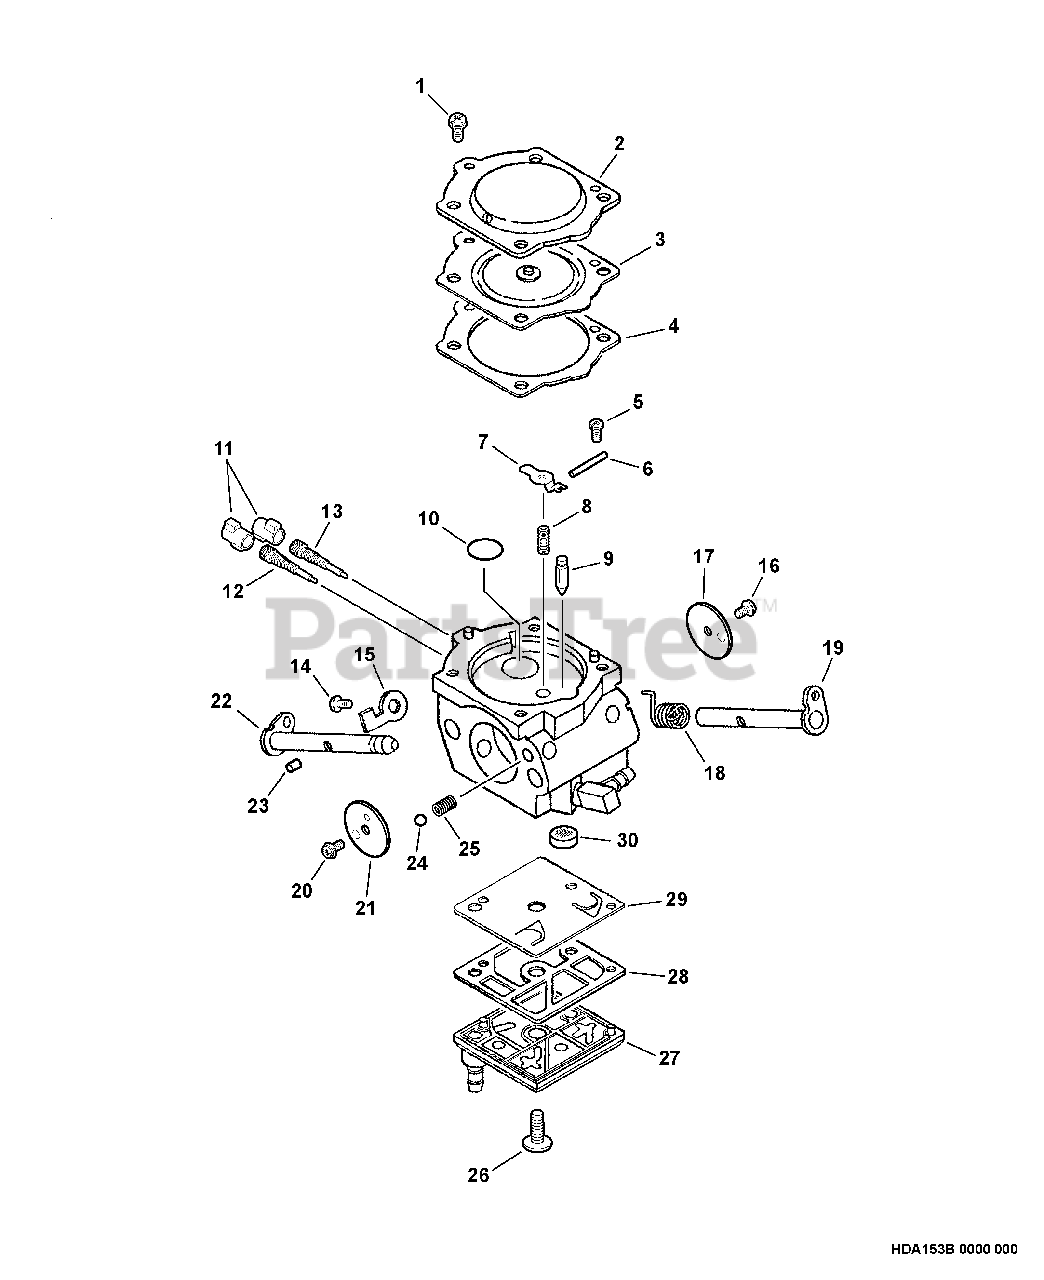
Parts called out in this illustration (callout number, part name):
2	COVER, METERING
3	DIAPHRAGM, METERING
4	GASKET, METERING
5	SCREW, METERING LEVER PIN
6	PIN, METERING LEVER
7	LEVER, METERING
8	SPRING, METERING LEVER
9	VALVE, INLET NEEDLE
10	PLUG, WELCH
11	CAP, LIMITER
12	NEEDLE - HIGH SPEED
13	NEEDLE - MIXTURE
15	STOP, THROTTLE
17	VALVE, THROTTLE
18	SPRING, THROTTLE RETURN
19	SHAFT, THROTTLE
21	VALVE, CHOKE
22	SHAFT, CHOKE
24	BALL, CHOKE
26	SCREW, PUMP COVER
27	COVER, PUMP
28	GASKET, PUMP
29	DIAPHRAGM, PUMP
30	STRAINER
A	REPAIR KIT
B	DIAPHRAGM/GASKET KIT
